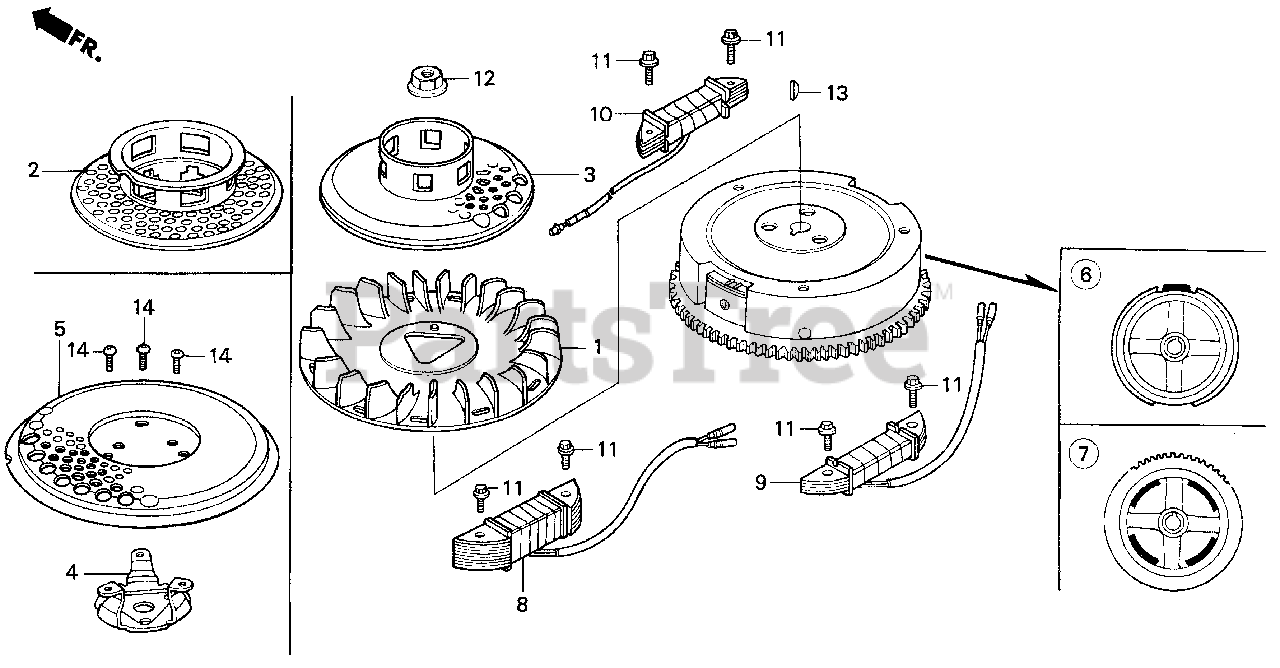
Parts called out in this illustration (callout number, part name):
1	FAN, COOLING
2	PULLEY, STARTER
3	PULLEY, STARTER (SCREEN GRID)
7	FLYWHEEL
9	COIL ASSY., CHARGE
11	BOLT, FLANGE (6X28)
12	NUT, SPECIAL (16MM)
13	KEY, SPECIAL WOODRUFF (25X18)
